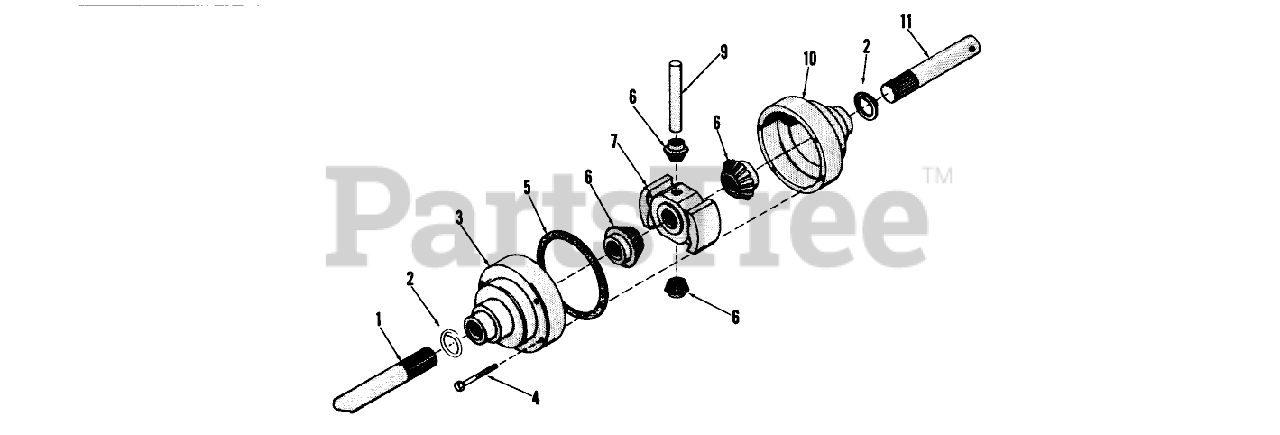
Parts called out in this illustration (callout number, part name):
1	Axle-Long
2	Snap Ring
3	Housing
4	Hex Head Bolt
5	Gasket
6	Bevel Gear Pinion Kit
7	Differential Cross
9	Pinion Shaft
10	Housing-Tapped
11	Axle-Short
